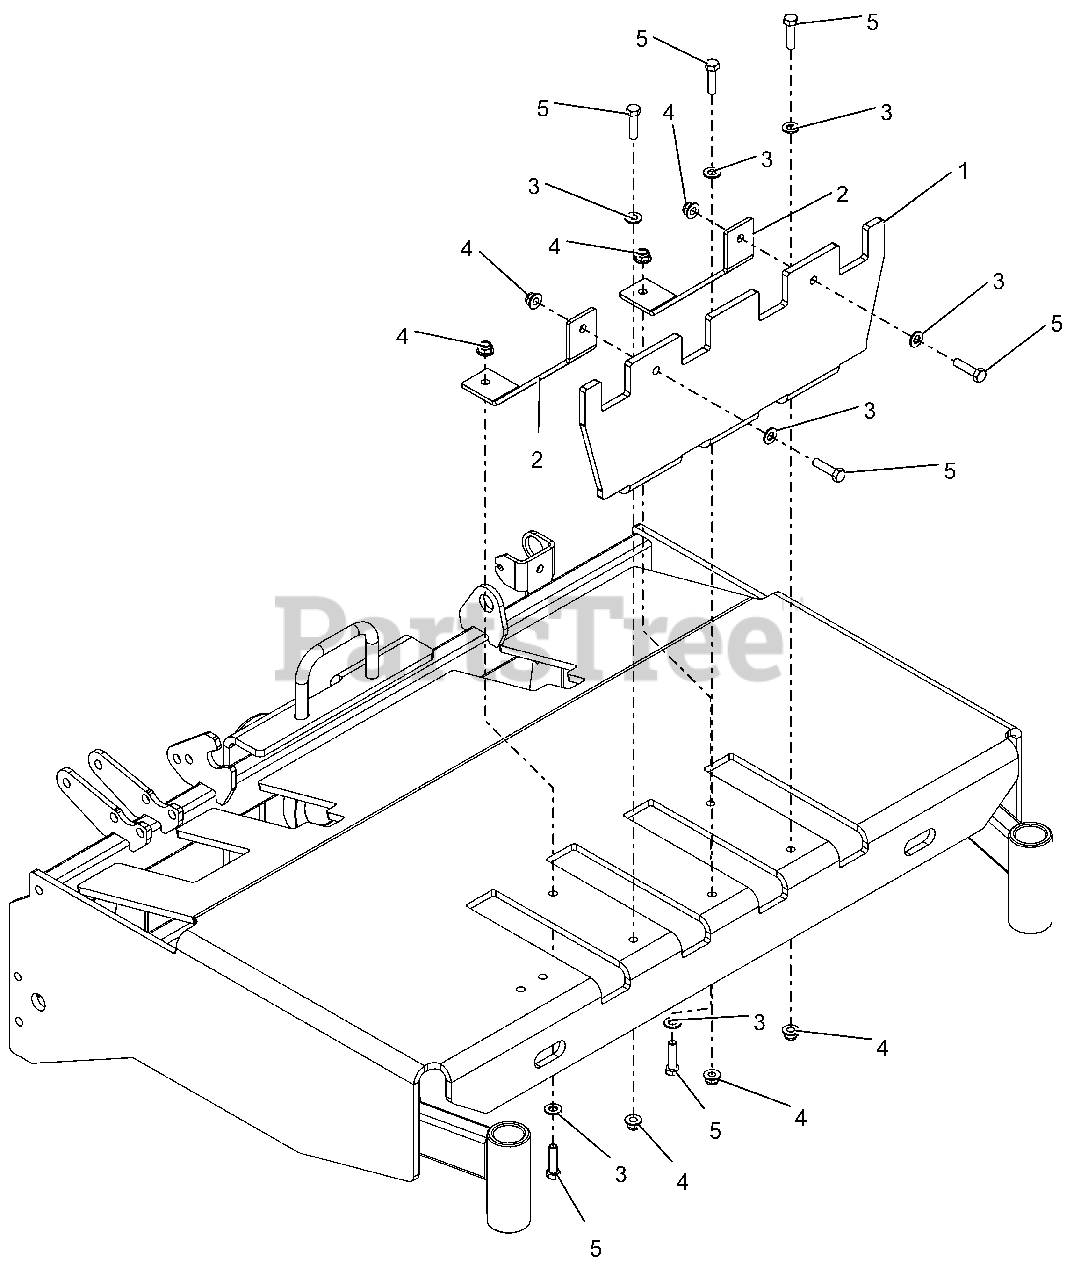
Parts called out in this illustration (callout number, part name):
1	BRKT, WEIGHT (RED)
2	BRACE, FRONT
3	WSHR,FLT .344X.688X.065 ZCC
4	NUT,NYL-FLG .31-18 GF ZCC
5	BLT, HEX .31-18X1.25 G5 ZCC
